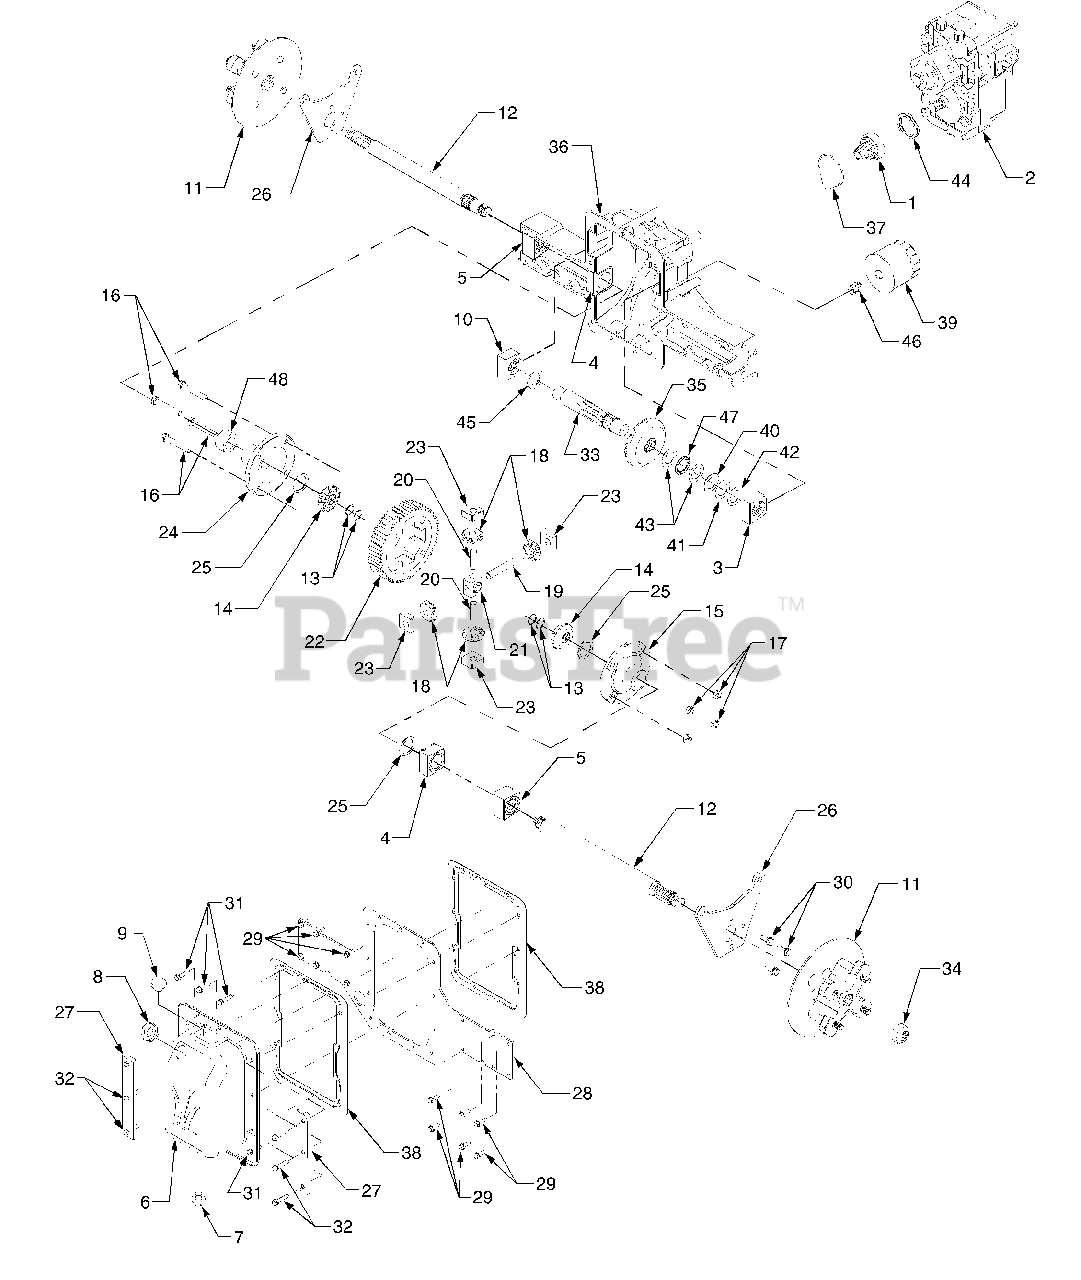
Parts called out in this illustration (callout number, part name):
1	Gear Assembly, Pinion 13T
2	Hydrostatic Transmission Assy. Kit
3	Bearing Block Assembly, Needle
4	Bearing Block Assembly
5	Bearing Block Assembly
6	Cover Assembly, Rear
7	Plug, Drain, M14 x 1.5 x .827
8	Grommet, Rubber
10	Bearing Block Assembly
11	Hub Assembly, Wheel
12	Axle Shaft, 15.08 Long
13	Retaining Ring
14	Gear, Spur, 14T
15	Housing, Diff. Cover
16	Hex Cap Screw, 3/8-24 x 2.25 GR5
17	Nut, Hex Lock, 3/8-24
18	Gear, Differential 10T
19	Shaft, Cross, .5 x 3.485
20	Shaft, Cross, Special
21	Differential Pinion Block
22	Gear, Spur 60T
23	Block, Thrust Miter
24	Housing, Differential Cover
25	Washer, Flat, 1.187 x 1.56 x .062
26	Bracket, Brake Mounting
27	Block, Transmission Cover
28	Plate, Transmission
29	Screw, Hex Wash. Hd. Tapp 1/4-20 x .75
30	Screw, Hex Wash. Hd. Tapp 5/16-18 x .875
31	Screw, Hex Wash. Hd. Tapp 1/4-20 x 1.0
32	Screw, Hex Wash. Hd. Tapp 1/4-20 x 1.25
33	Shaft, Output 9T
34	Nut, Lock, 7/8-14
35	Gear, Bevel 54T
36	Differential Housing Service Kit
37	O-Ring, 2.75 x .103
38	Gasket
39	Filter, Oil
40	Washer, Flat Shim, 1.0 x 1.56 x .010
41	Washer, Flat Shim, 1.0 x 1.56 x .020
42	Washer, Flat Shim, 1.0 x 1.56 x .015
43	Washer, Thrust, 1.007 x 1.542 x .03
44	Washer, Spring
45	Washer, Flat, 1.01 x 1.86 x .060
46	Fitting, Filter Nipple
47	Bearing, Needle Thrust
48	Spacer, Axle, 1.188 x 1.665 x .67
